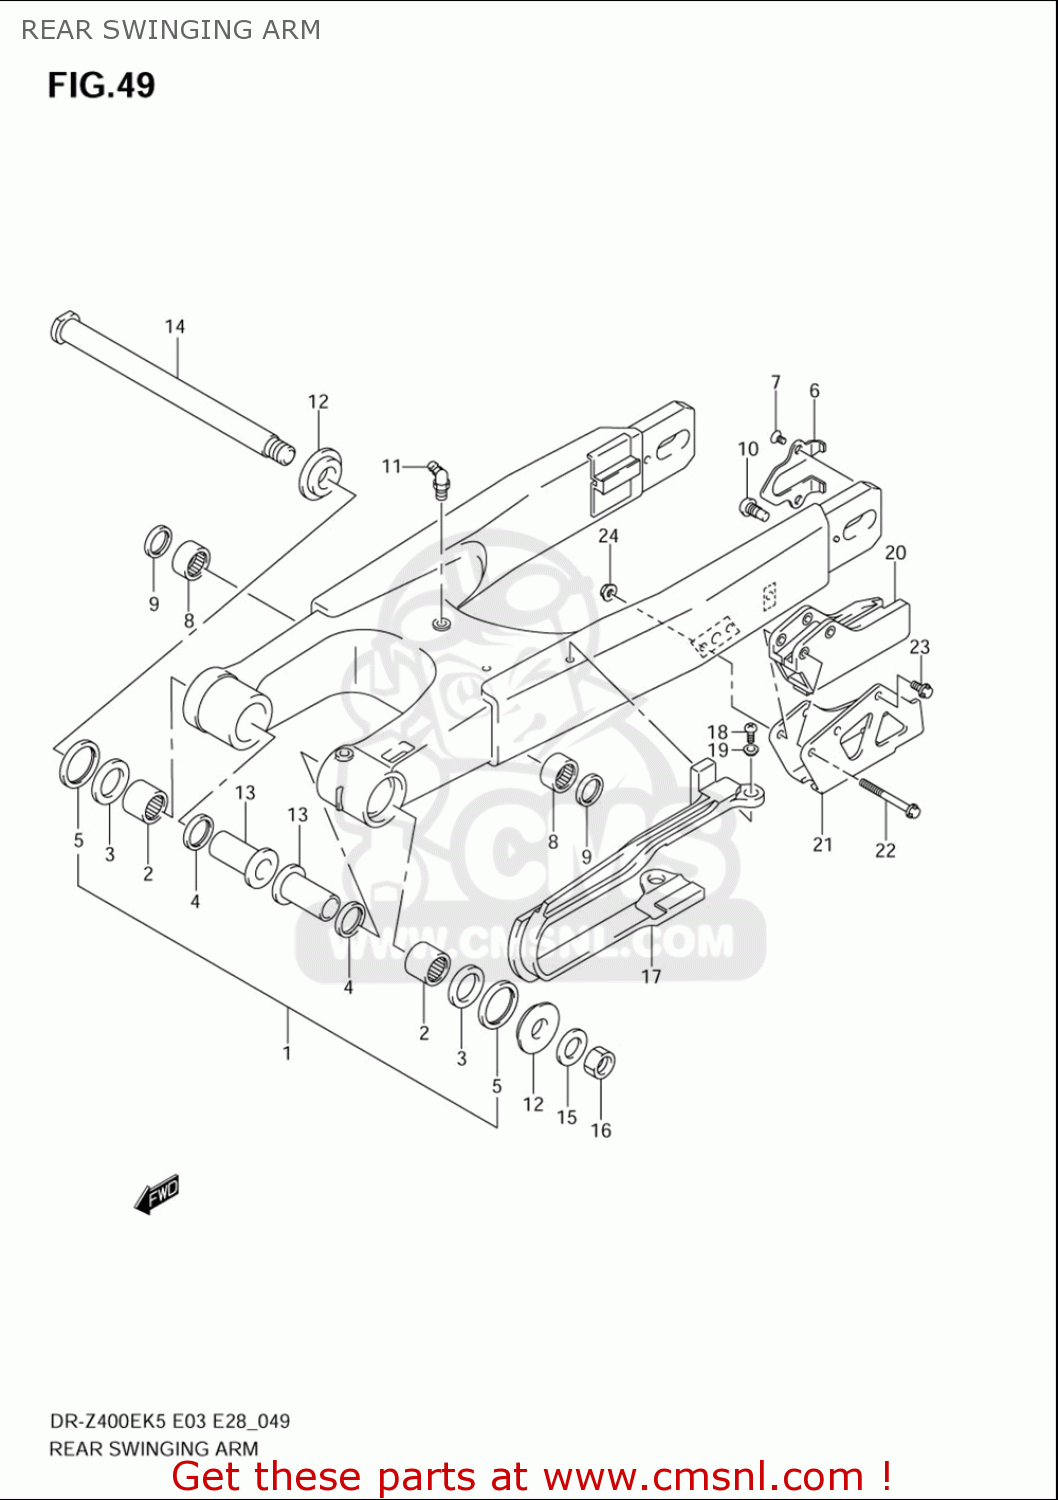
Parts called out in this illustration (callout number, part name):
1	SWING ARM ASSEMBLY,REAR
2	BEARING(22X29X30)
3	BEARING(22X35X2)
4	SEAL,OIL(22X29X4)
5	SEAL,RR SWGARM PIVOT OUTER
6	PLATE,RR SWING ARM AXLE
7	SCREW(5X8)
8	BEARING(20X27X15)
9	SEAL,CUSHION LEVER DUST
10	STOPPER,CHAIN ADJUSTER
11	NIPPLE,GREASE
12	SPACER,SWINGINGARM PIVOT OUTER
13	SPACER,SWGARM PIVOT INNER
14	SHAFT,RR SWINGINGARM PIVOT
15	WASHER
16	NUT
17	BUFFER,CHAIN TOUCH DEFENSE
18	SCREW
19	WASHER
20	GUIDE,CHAIN
21	PLATE,CHAIN GUIDE
22	BOLT
23	BOLT
24	NUT
